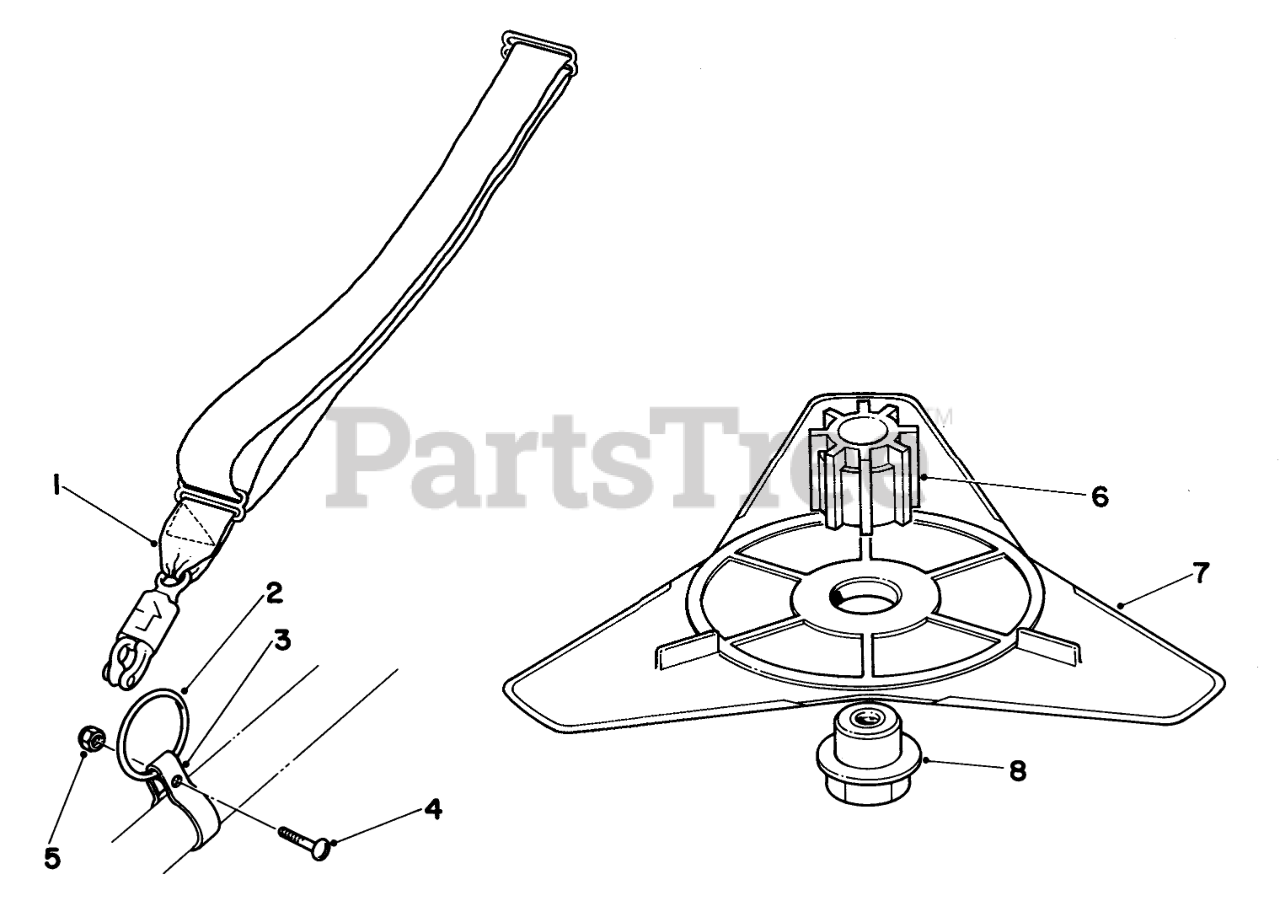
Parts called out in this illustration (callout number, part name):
1	Shoulder Strap
2	Ring
3	Clamp
4	Screw
5	NUT-LOCK, NI
6	BLADE ADAPTER
7	FLEX BLADE PKG
8	ADAPTER NUT
